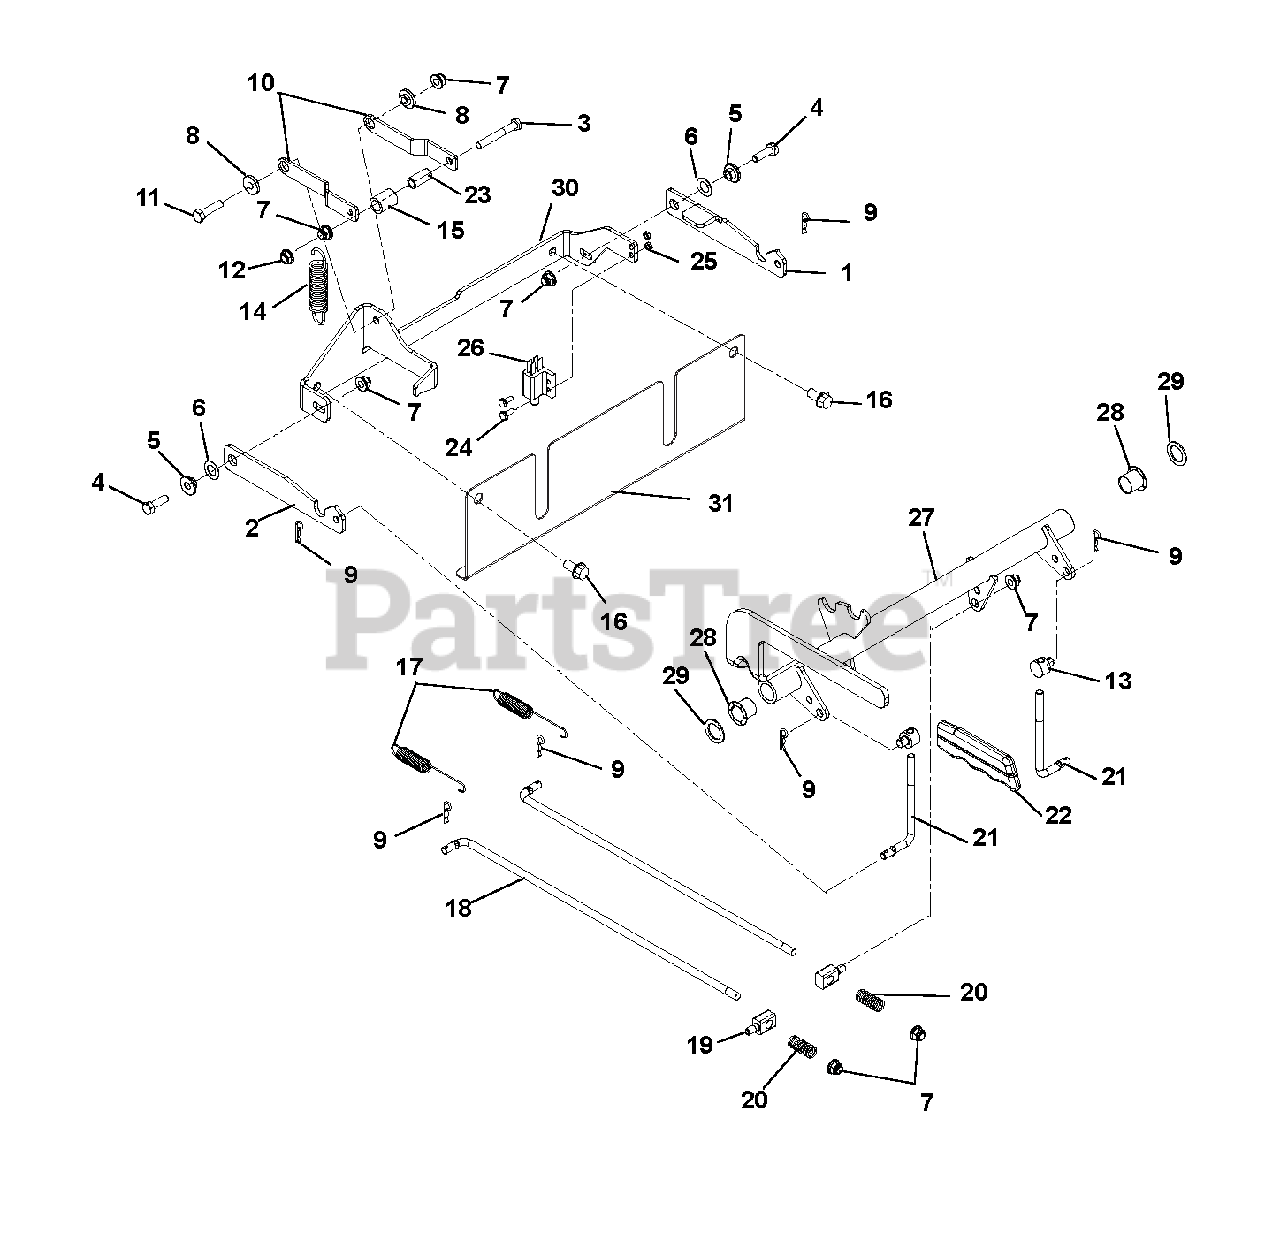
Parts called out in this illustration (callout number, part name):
1	LINK, BRAKE INTERLOCK
2	INTERLOCK, BRAKE
3	@BLT-HEX .31-18X2.25 GR5 YWZC
4	@BLT-HEX .31-18X1.00 GR5 YWZC
5	BSHG-FLG .32X.500X.344X.880
6	WSHR-FL-STL .505X.875X.024 YWZ
7	@NUT-LK-NYL-FLG .31-18 YWZC
8	BSHG, FLG .325X.499X.26X.88
9	PIN-HAIR INT .08X.18X1.18 YWZC
10	ARM, BRAKE CAM
11	@BLT-HEX .31-18X1.25 GR5 YWZC
12	@NUT-LK-TOP-FLG .31-18 YWZC
13	TRUNNION, BRAKE .31-18 UNC
14	SG-TENS .105X.812X3.88 WLD 15
15	ROLLER, CAM LOCK
16	@SCR-TAP .38-16X.75 HWH TR YWZ
17	SG-TENS .056X.60X4.40
18	ROD, PARK BRAKE
19	PIN, PIVOT/TRUNNION
20	SPRING, COMPRESSION
21	LINK, INTERLOCK BRAKE
22	GRIP, PARKING BRAKE (YELLOW)
23	BSHG, SPCR .330X.500X1.01 PM
24	@SCR-MCH 10-24X.50 HWH YWZC
25	@NUT-LK-NYL 10-24 W/INSRT YWZC
26	SWITCH- DOUBLE POLE N.O./N.O.
27	SHAFT, BRAKE
28	BUSHING, IGLIDE CLIP
29	WSHR-FL-STL.754X1.125X.062YWZC
30	BRKT, BRAKE MTG
31	BRKT, LOWER FINGER GUARD - XL
